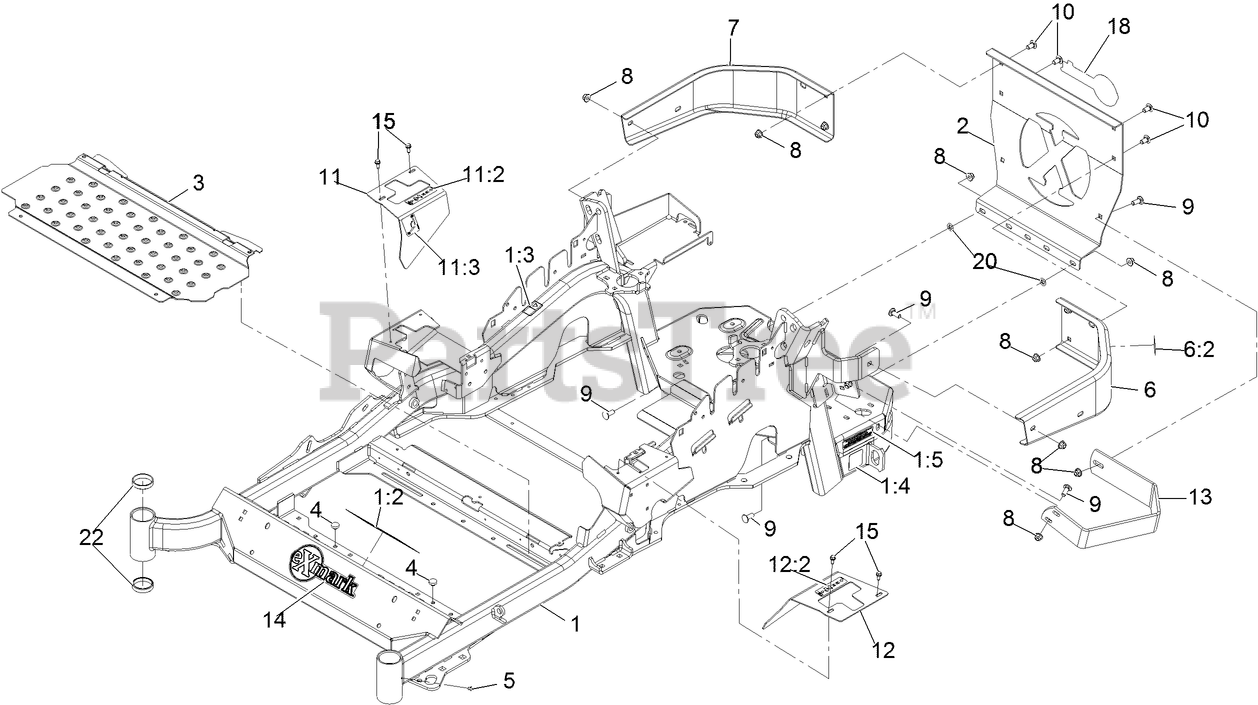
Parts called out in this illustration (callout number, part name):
1	MAINFRAME ASM
1:2	DECAL-DANGER
1:3	DECAL-WARNING
1:4	DECAL-HAZARD, PINCHED FINGER
1:5	DECAL-ARRESTOR, SPARK
2	PLATE,REAR GUARD
6	LH BUMPER ASM
6:2	DECAL-WARNING
7	BUMPER-RH
8	NUT-HF, NI
9	SCREW-CARR
10	SCREW-CARR
11	RH MOTION CONTROL COVER ASM
11:2	DECAL-CONTROL, MOTION
11:3	DECAL-PARK BRAKE, CE
12	LH MOTION CONTROL COVER ASM
12:2	DECAL-CONTROL, MOTION
13	GUARD-MUFFLER
14	DECAL-EXMARK
15	SCREW-HWH
18	DECAL, EXMARK LOGO
20	NUT-PUSH
22	CUP-BEARING
